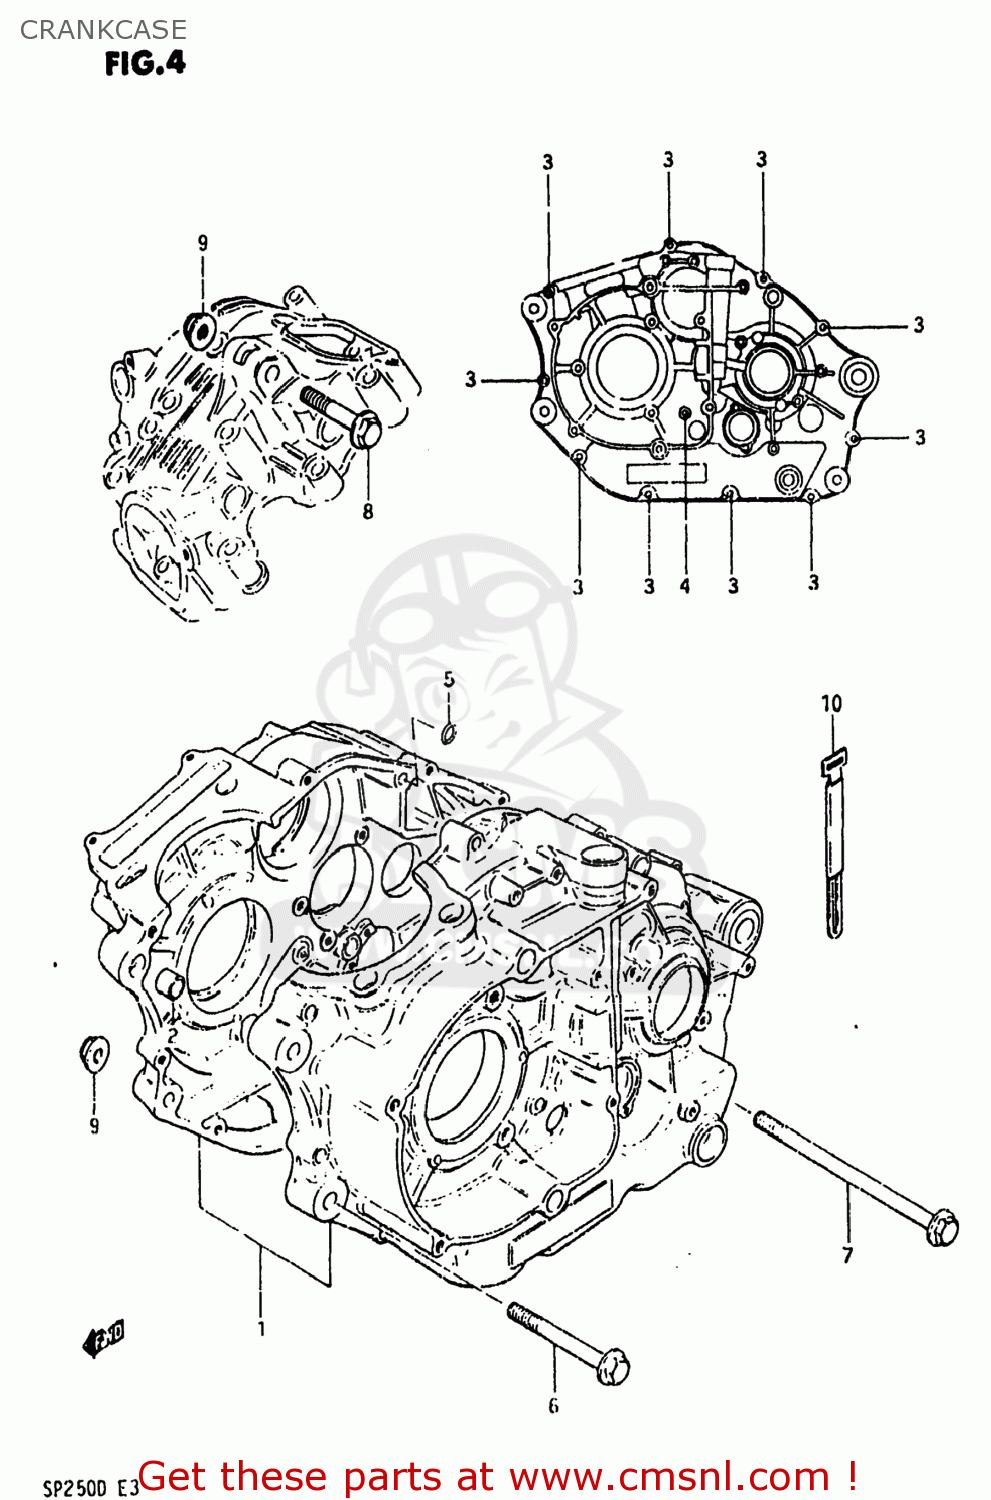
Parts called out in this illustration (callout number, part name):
1	CRANKCASE SET
2	PIN
3	BOLT (6X35)
4	BOLT (6X55)
5	O-RING
6	BOLT 8X67
7	BOLT
8	BOLT 8X50
9	NUT
10	CLAMP L:110
